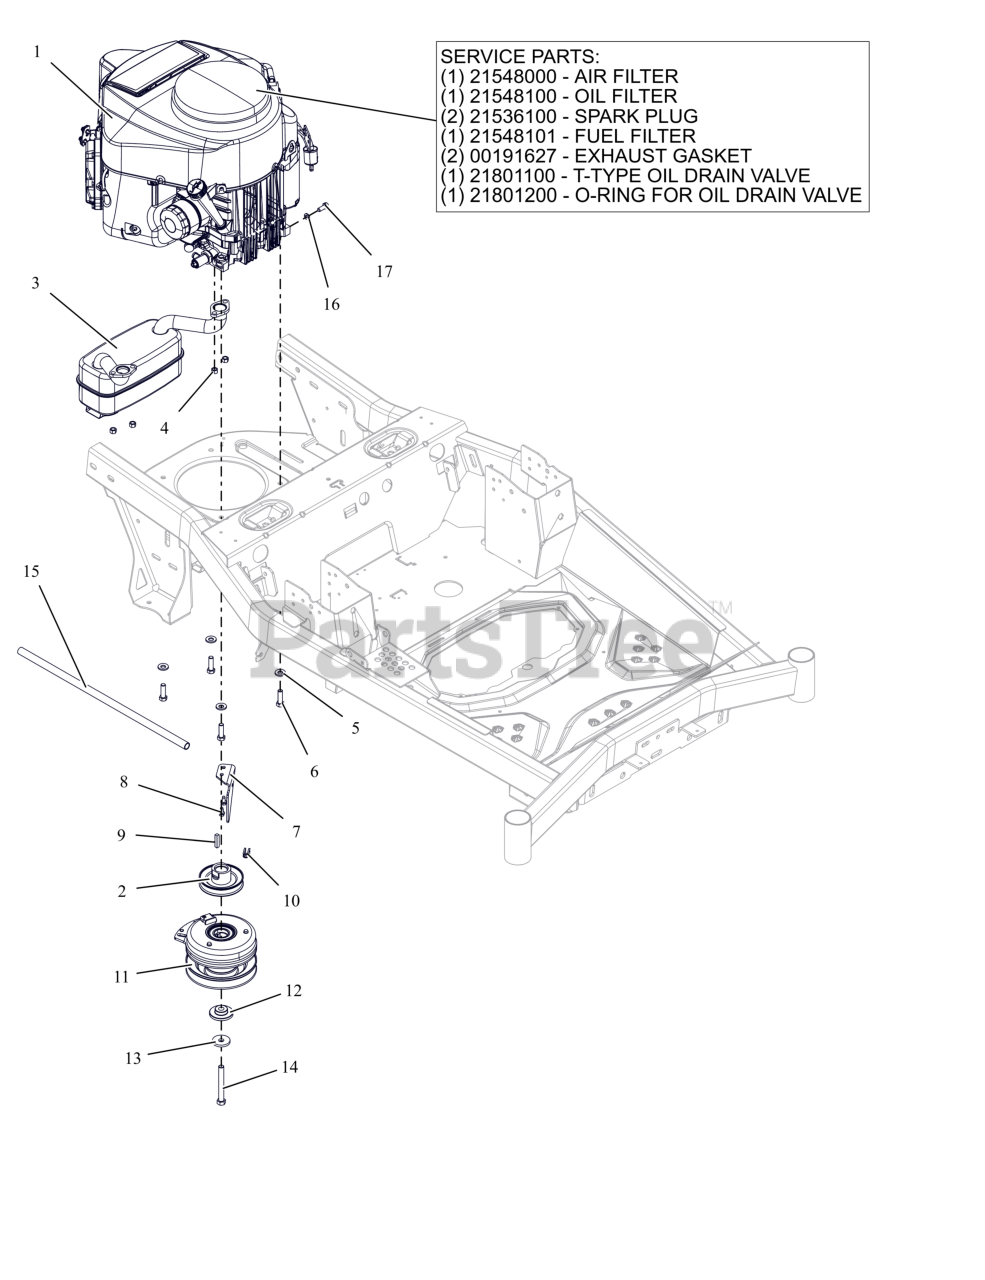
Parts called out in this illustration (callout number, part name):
1	ENGINE, KAWASAKI FR691 23HP
1	AIR FILTER, KAWASAKI FR
1	OIL FILTER, KAWASAKI FR
1	PLUG, SPARK
1	FUEL FILTER-KAWASAKI FR
1	GASKET, MUFFLER S/O
1	VALVE- T-TYPE OIL DRAIN
1	O-RING- OIL DRAIN VALVE
2	WLDMT-PULLEY-4.831OD X1.003
3	MUFFLER - KAWASAKI
4	NUT-LK-TOP-FLG M8 ZCC
5	WASHER, 3/8" SPRING DISC
6	BLT, HEX .38-16X1.25 G5 ZCC NT
7	BRKT- CLUTCH STOP
8	SCR-TAP .25-20X.50 HWH ZCC
9	KEY-SQ .25 X 1.25 X .25 SAE
10	BSHG, CLUTCH
11	CLUTCH, WARNER-IXR-18211
12	BSHG-FLG .469X1.06X.574X2.0
13	WASHER, 7/16" SPRING DISK
14	BLT- HEX .44-20X3.50 G8 ZCC NT
15	HOSE- OIL DRAIN
16	WSHR,LK-REG .312X.078 ZCC
17	BLT, HEX M8-1.25X20 G8.8 ZCC
